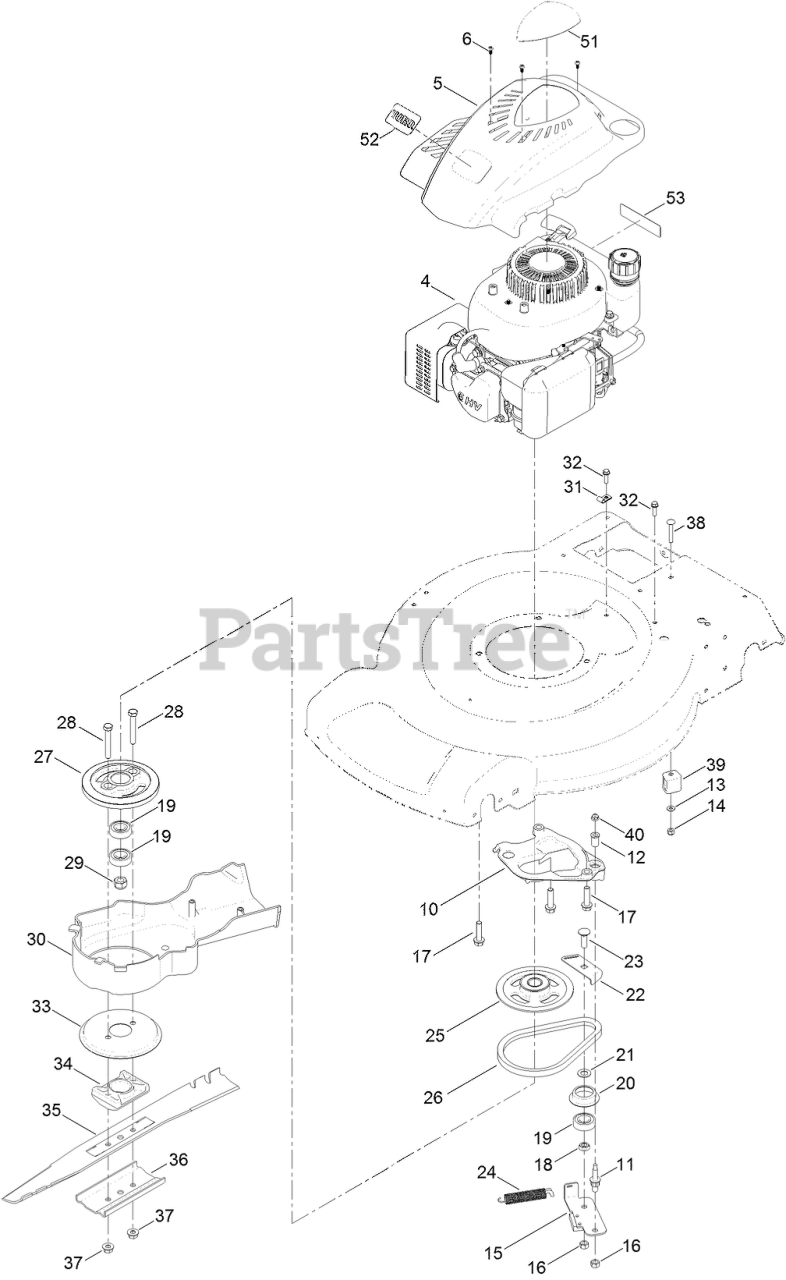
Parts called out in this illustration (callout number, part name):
4	ENGINE-1P65FC
5	SHROUD
6	SCREW-PPH
10	PLATE-ANCHOR
11	BOLT-SHOULDER
12	BUSHING
13	WASHER-FLAT
14	NUT-LOCK, NI
15	PLATE-BRAKE
16	NUT-HEX
17	SCREW-HWH
18	SPACER-BEARING
19	BEARING-BALL
20	RETAINER-BELT
21	WASHER-PLAIN
22	PLATE-GUIDE
23	BOLT-CARR
24	SPRING-TENSION, BRAKE
25	PULLEY
26	BELT
27	DRUM
28	SCREW-HH
29	NUT-HEX
31	CLIP-CLOSED, INSULATED
32	SCREW-HWH
33	DISC
34	SUPPORT-BLADE
35	BLADE-22 INCH
36	SUPPORT-BLADE
37	NUT-FLANGE, LOCK
38	SCREW-CARR
39	ANCHOR-CABLE
40	NUT-HF
51	DECAL-SHROUD
53	DECAL-ARRESTER, SPARK
